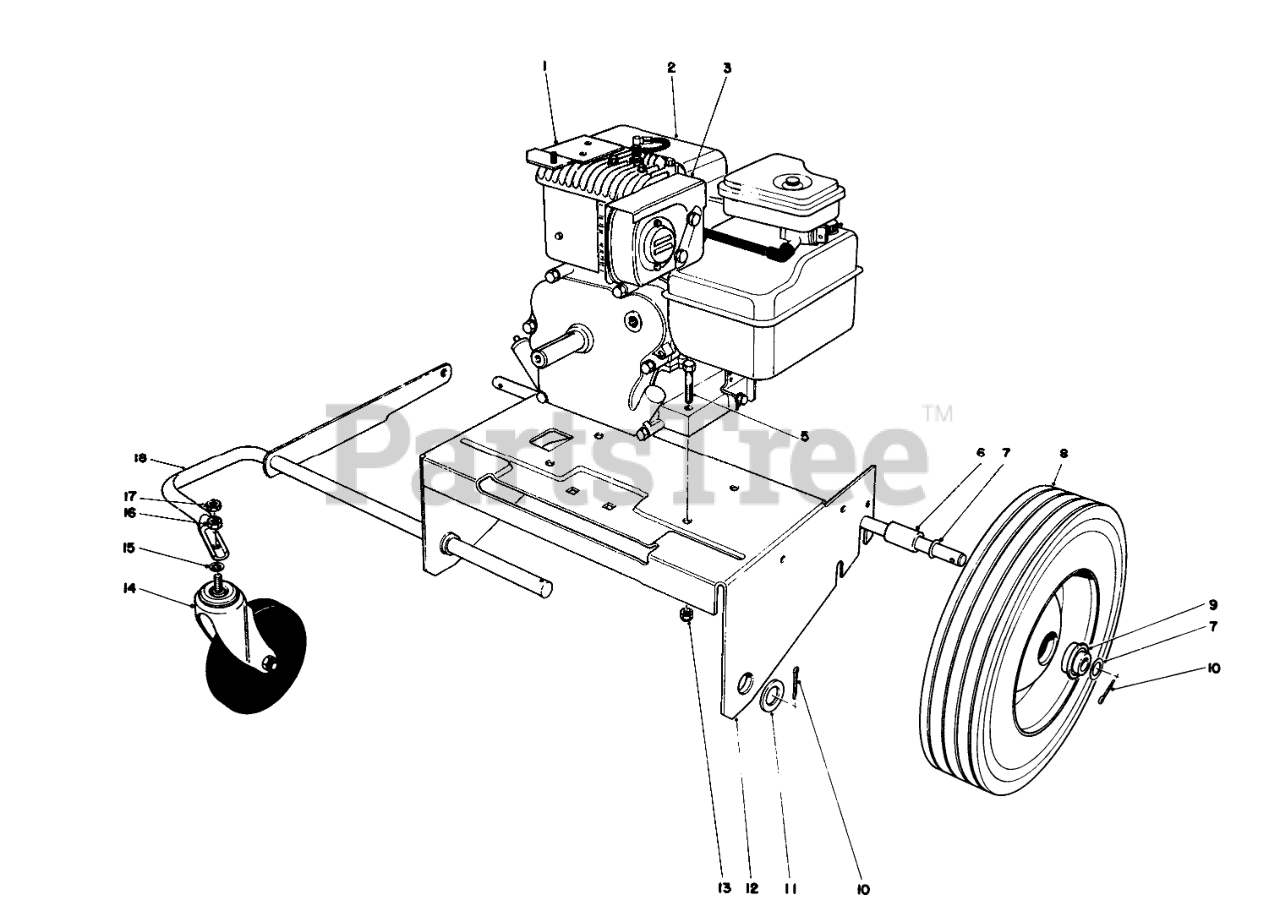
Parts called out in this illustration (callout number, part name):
1	MTG BRKT WA B
2	Engine
3	HEAT SHIELD
5	SCREW-HH
6	SPACER-AXLE
7	WASHER
8	Wheel (Incl. Ref. #9)
9	BEARING
10	PIN-COTTER
11	WASHER-FLAT
12	Engine Plate
13	NUT-LOCK, CONE
14	CASTER
15	Lockwasher
16	NUT-HH
17	1/2-13 CONELOCK NUT
18	Front Wheel Support
